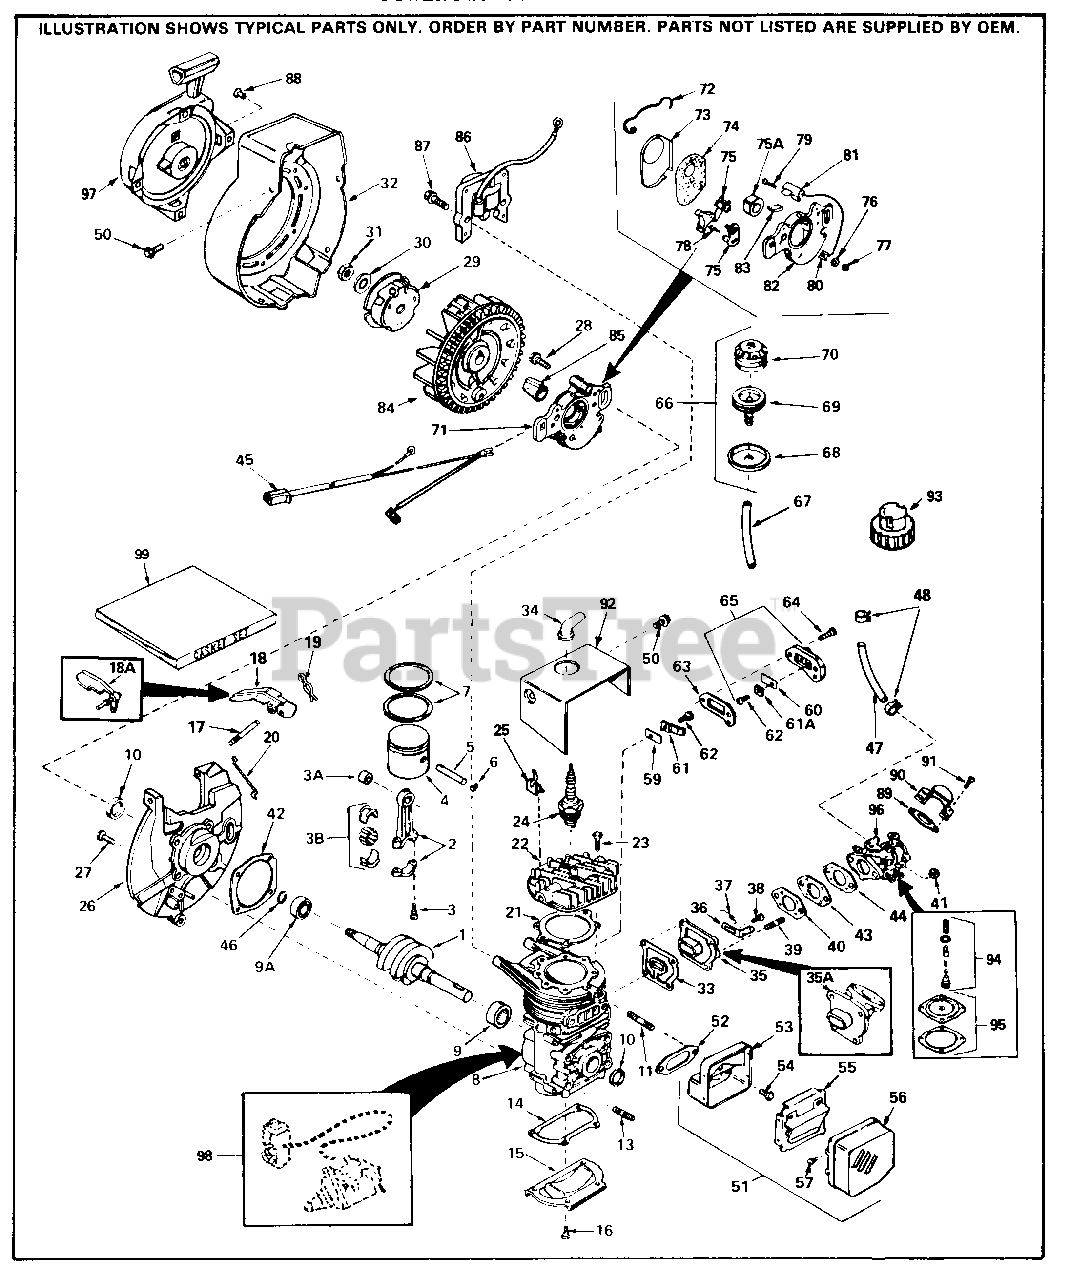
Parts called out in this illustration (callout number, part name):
1	"Crankshaft
2	Rod Assy., Connecting Incl. 3, 3A & 3 B
3	Screw, Connecting rod
3A	Bearing, Cartridge
3B	Bearing & Liner Set, Needle
4	Piston
5	Pin, Piston
6	Ring, Piston pin retaining
7	Ring Set
8	Cylinder Order s/b if replacement is req.
9	Bearing, Cartridge
9A	Bearing, Ball
10	Seal, Crankshaft
11	Stud, Exhaust
14	* Gasket, Cover
15	Plate, Cover
16	Screw, Torx T-25, 10-24 x 1/2"
18A	Vane, Air
20	Link, Governor
21	* Gasket, Cylinder head
22	CYL HEAD
23	Screw, T-30, 1/4-20 x 3/4"
24	Plug, Spark (RJ-18Y)
26	Base Assy., Blower housing (Incl. 10)
27	Screw, 1/4-20 x 5/8"
28	Screw, 1/4-20 x 3/4"
29	Cup, Starter
31	Nut, Flywheel
32	BLOWER HSG
33	* Gasket, Port
34	Cover, Spark plug
35	Adapter Assy. (Incl. 39)
36	Lever, Adjusting
37	Spring, Adjusting lever
38	Screw, 10-24 x 5/8"
39	Stud, Carburetor
40	* Gasket, Carburetor (1/8" thick)
41	Nut
42	* Gasket, Blower housing base
44	* Gasket, Carburetor (1/16" thick)
45	Harness, Wire
46	Ring, Retaining (Use as required)
50	Screw, T-30, 1/4-20 x 3/8"
52	* Gasket, Exhaust
66	Primer Assy. (Incl. 69 & 70)
67	Line, Primer
68	Retainer, Primer bulb
69	Body, Primer
70	Bulb, Primer
71	Plate Assy., Stator Incl. 72 & 76 thr u 83
72	Spring, Breaker box cover
73	Cover, Dust
74	Gasket, Dust cover
75	Breaker Points (also available in Pac kaged Part #740037B)
75A	Cam, Breaker
78	Screw, 8-32 x 5/16"
79	Screw, Condenser
80	Terminal, Ground
81	Condenser (also available in Packaged Part #740037B)
82	Plate, Stator
83	Felt, Cam wiper
84	Flywheel
85	Sleeve, Keyed Adapter
86	Lamination & Coil Assy. (Incl. 34)
87	Screw, 10-24 x 1"
88	Rivet, Pop (3/16" Dia.) Purchase loc ally
93	Cap, Fuel tank
94	Inlet Needle, Seat, Gasket & Spring A ssy.
95	Diaphragm Assy.
96	Carburetor (Incl. 41) (Refer to Divis ion 5, Section A, page 172 for breakd own)
97	Rewind Starter Refer to Division 5, S ection C, page 25 for breakdown
98	Starter Motor Kit (110-120 Volt) (Opt i onal) (Refer to Division 5, Secti on D, page 24 for breakdown)
99	* Gasket Set (Incl. items marked *)
